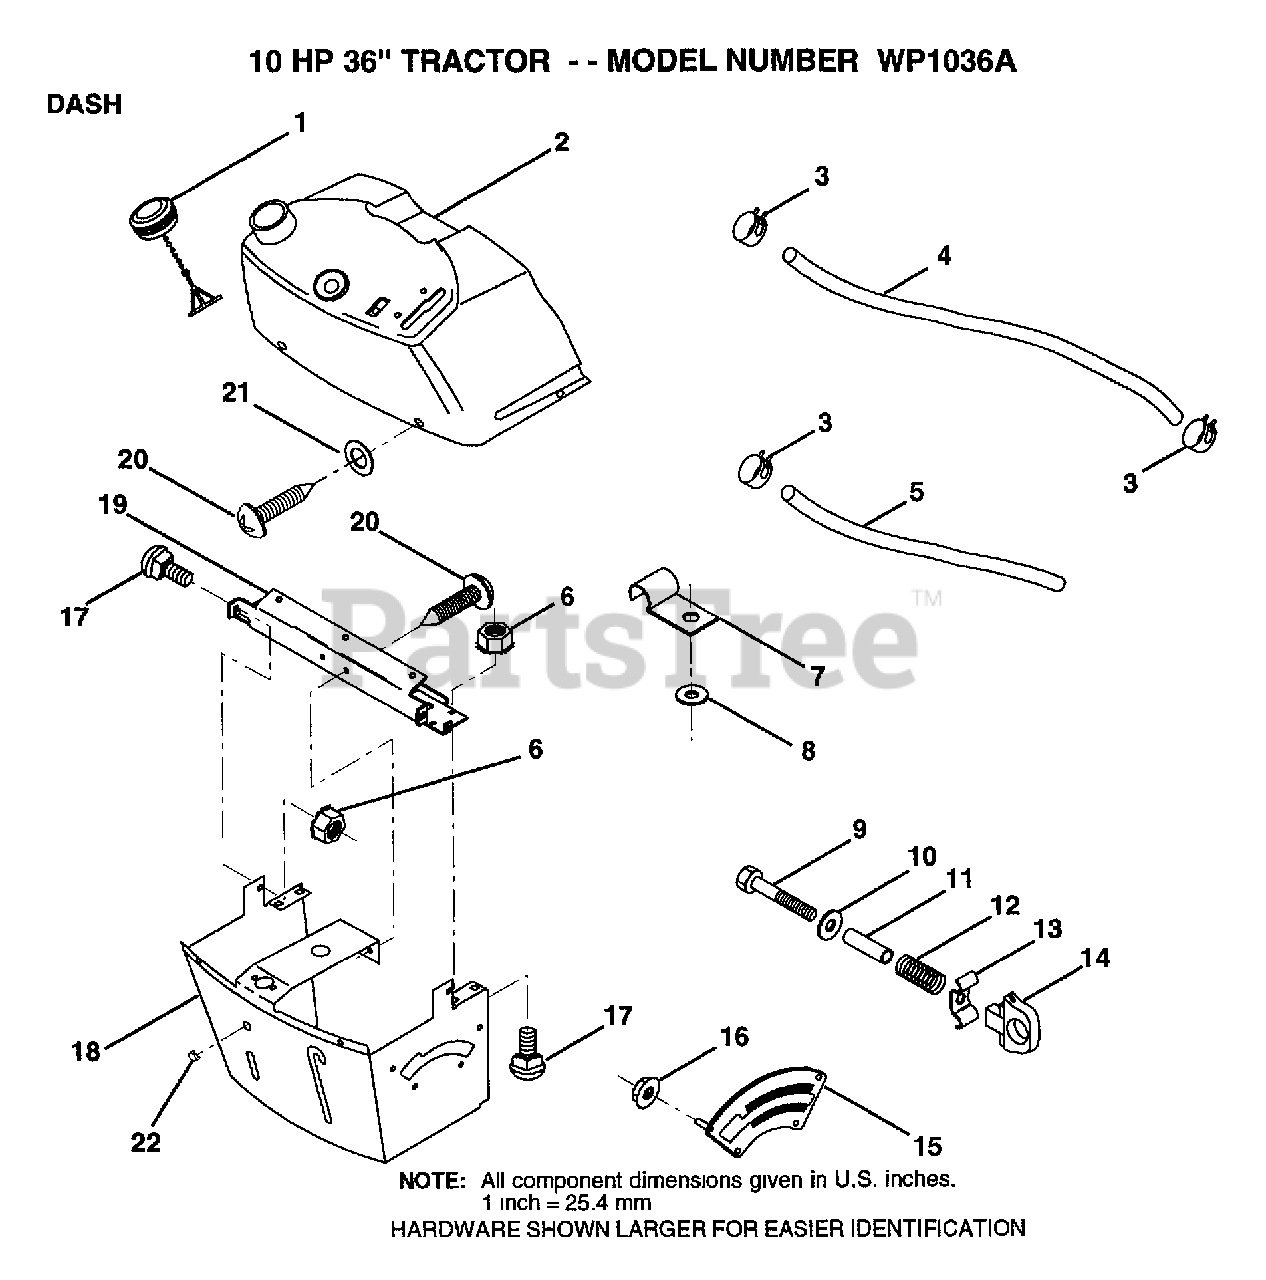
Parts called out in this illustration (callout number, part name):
3	HOSE CLAMP
5	FUEL LINE T
6	NUT
7	CLIP T
8	WASHER PM
9	BOLT
11	SPACER SPLIT
12	SPRING M
13	"KNOB,HGT RETAINER"
14	KNOB
15	ADJUSTER QUAD
16	NUT
17	BOLT
18	SUPT ASSY DASH
19	CROSS BRACE
22	PLUG DOME
